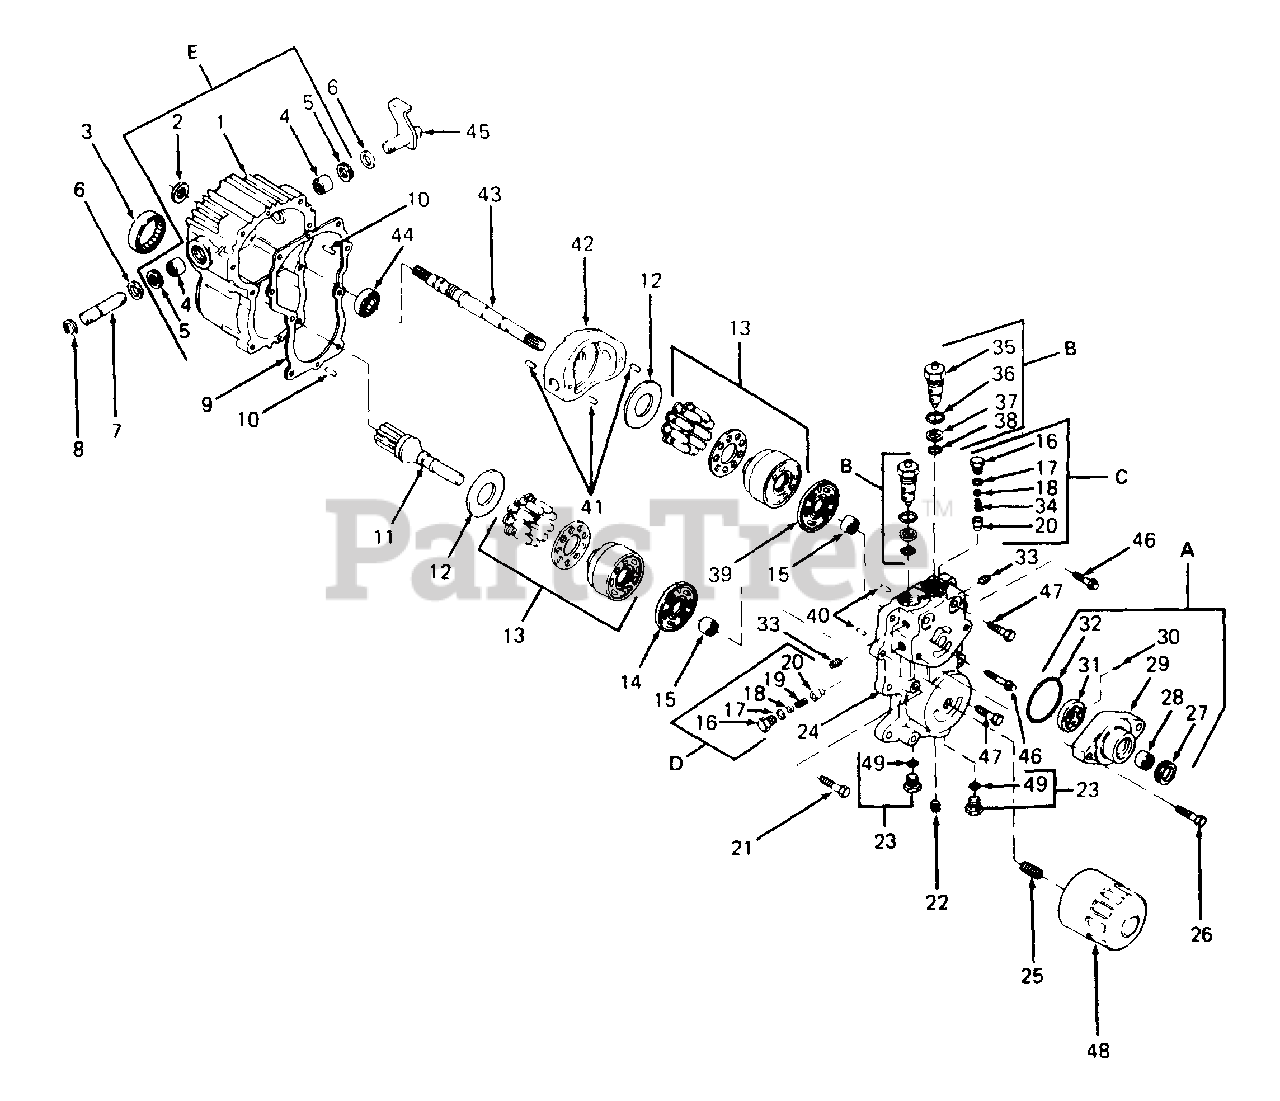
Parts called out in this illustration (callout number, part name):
1	Housing, Transmission
2	Seal, Lip
3	Bearing, Roller
4	Bearing, Needle
5	Seal, Lip
7	Shaft, Trunnion
8	Ring, Retaining
9	Gasket
10	Pin
11	Shaft, Motor
12	Plate, Thrust
13	Block, Cylinder
14	Plate, Valve
15	Bearing, Roller
16	Plug
17	O-Ring
18	Kit, Shim Pack
19	Spring, Center Relief Valve
20	Cone, Relief Valve
24	Center Section
27	Seal, Lip
28	Bearing, Needle
29	Charge Pump Housing
31	Gerotor
34	Spring, Implement Relief
35	Valve
37	Ring, Back-up
39	Plate, Valve
43	Shaft, Pump
44	Bearing, Ball
45	Shaft Assembly, Trunnion
46	Screw, 12 Point
48	Oil Filter
A	Kit, Charge Pump
B	Valve Assembly
C	Kit, Relief Valve
D	Kit, Relief Valve
E	Housing Assembly
